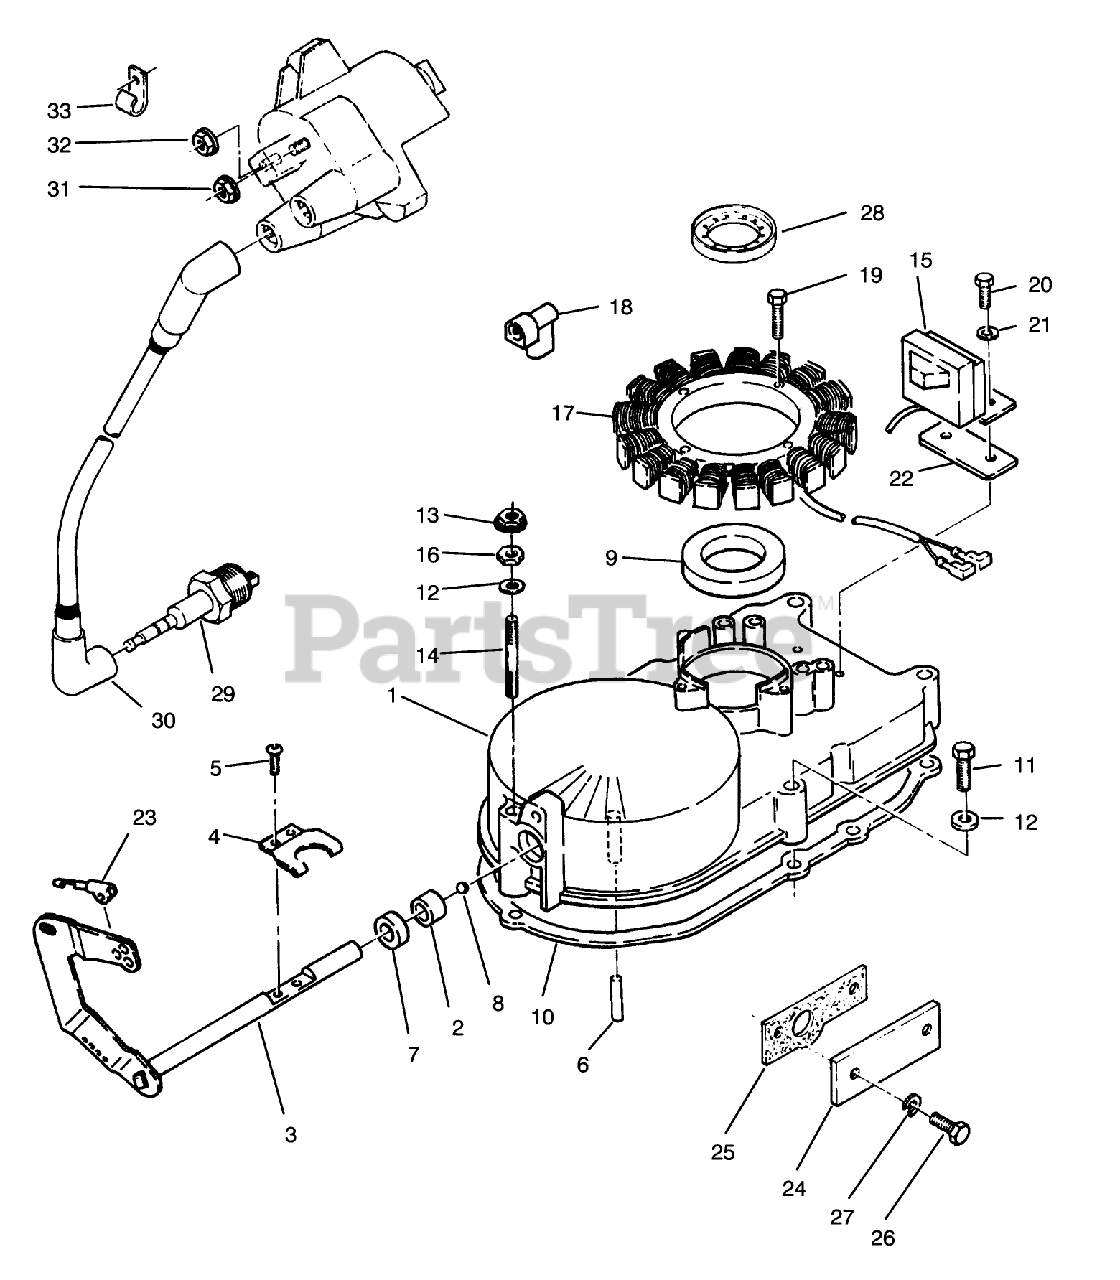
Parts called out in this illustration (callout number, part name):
1	GEAR-CASE KIT
5	SCREW-PAN HD
12	WASHER
16	NUT-GEAR COVER
25	GASKET
29	SPARK PLUG
